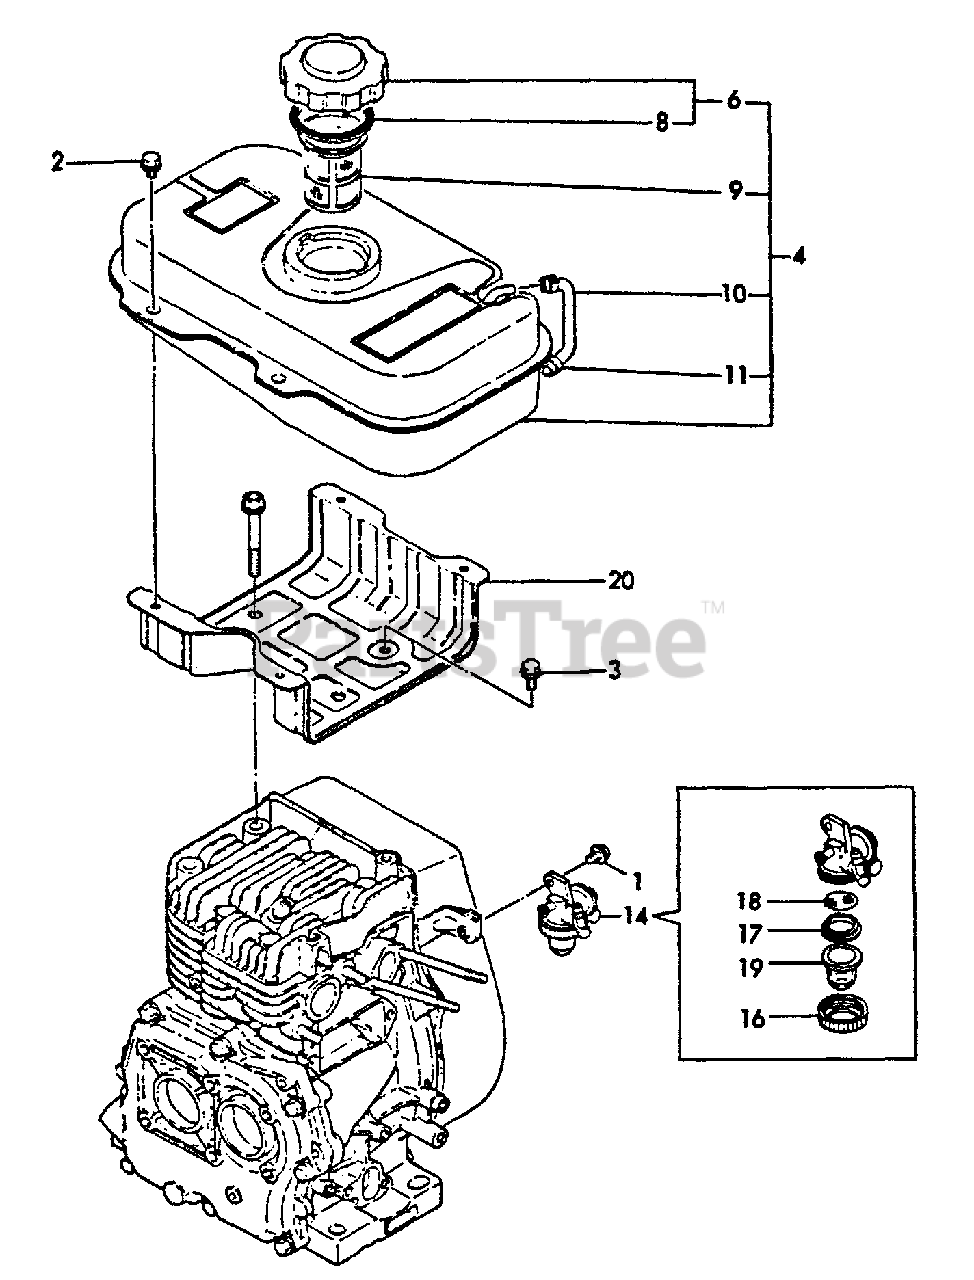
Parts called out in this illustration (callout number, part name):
1	BOLT - 6X8 -- PLATED
2	BOLT - 6X10 -- PLATED
3	BOLT - 6X8 -- PLATED
4	FUEL TANK ASSY
6	CAP ASSY
8	GASKET
9	STRAINER, FUEL
10	PIPE, GAUGE
11	CLAMP, HOSE - 9
14	FUEL COCK ASSY
16	RETAINER
17	GASKET
18	STRAINER, FUEL
19	BOWL, STRAINER
20	BRACKET, FUEL TANK
